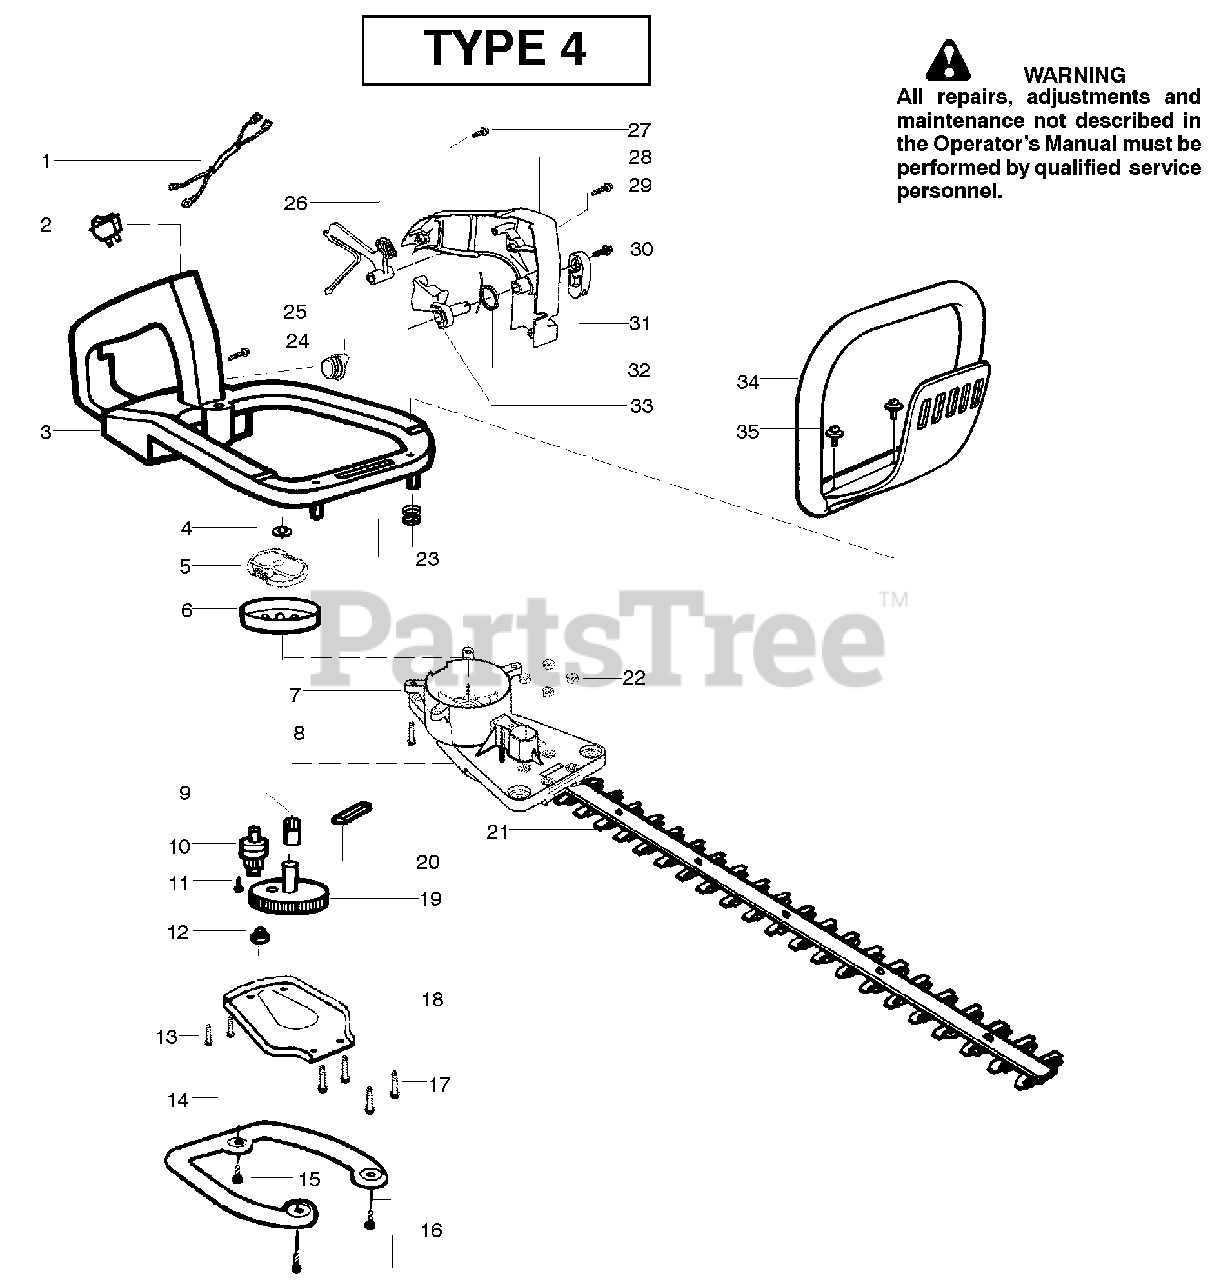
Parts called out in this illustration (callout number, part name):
1	Assy-Leadwire/Switch
2	Switch-Ignition
3	Assy-Rear Handle & Tank
4	Washer-Clutch
5	Kit-Clutch Assy.
6	Assy-Drum
7	Assy-Gear Box
9	Bearing-Gear
10	Assy-Pinion
11	Screw
12	Bushing-Blade
14	Plate-Isolator
18	Cover-Gear Box Plate
19	Kit-Drive Gear Ass'y.
20	Seal-Blade (Felt)
21	Assy-Blade 19"
24	Assy-Fuel Cap
26	Lockout-Throttle
28	Kit-Handle Cover
31	Lever-Trigger
32	Spring-Trigger
34	Handle-Front
